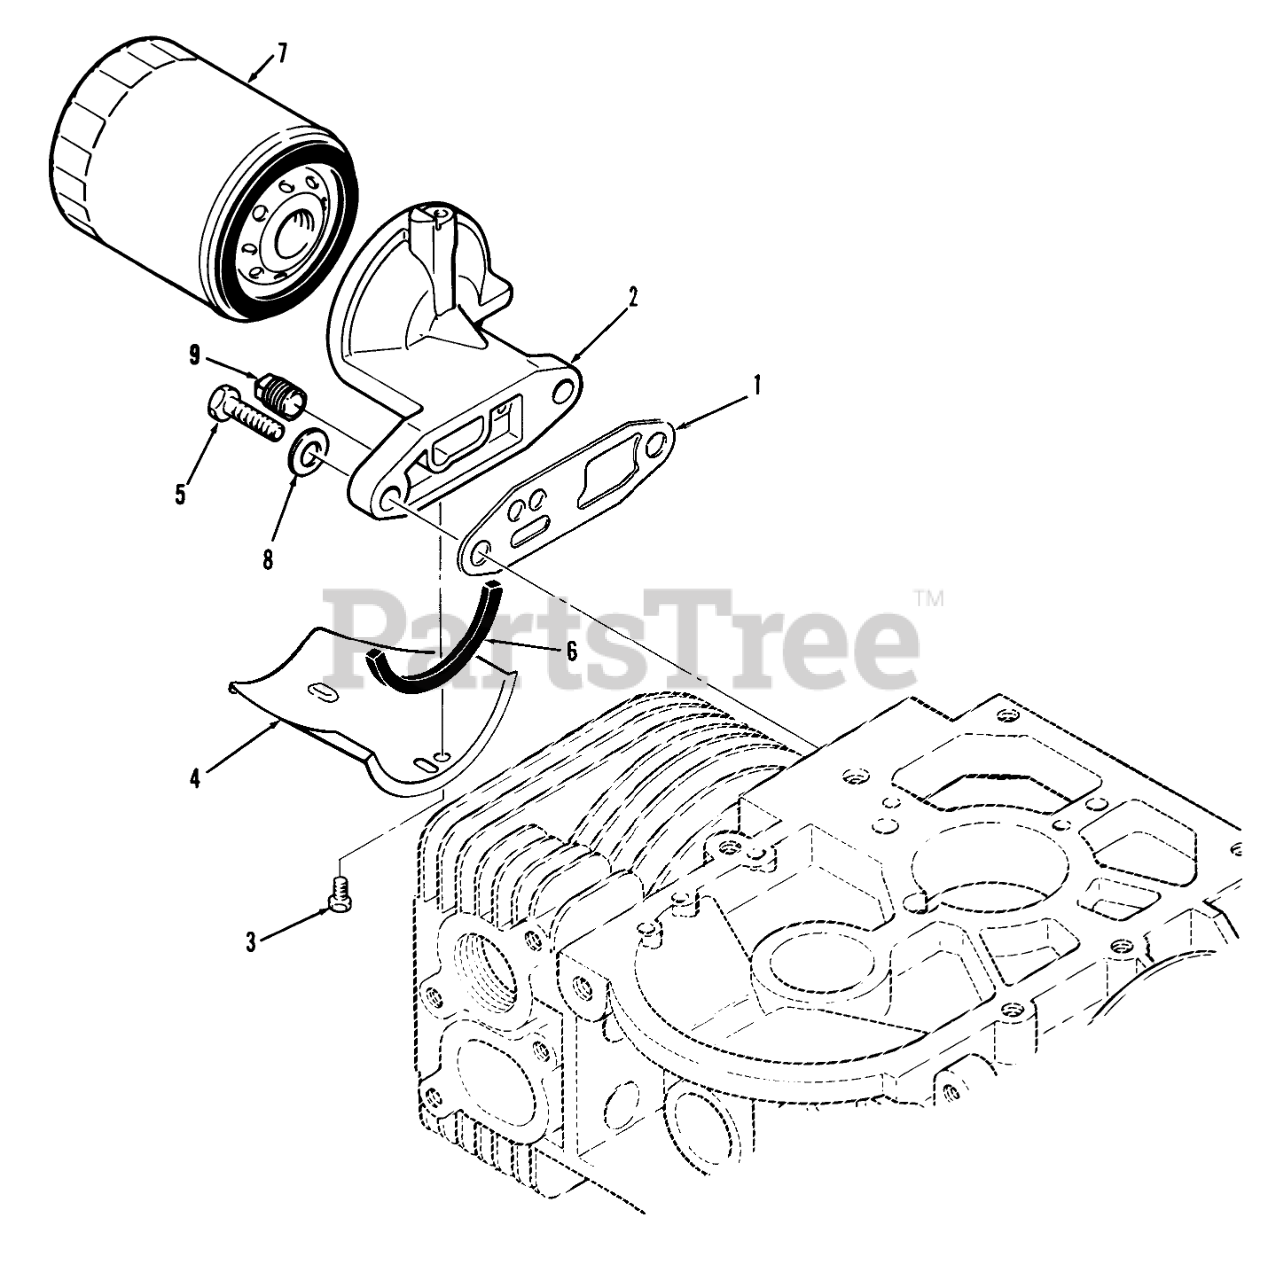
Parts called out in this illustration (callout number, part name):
1	Gasket
2	Adapter
3	Bolt
4	OIL-DRAIN
5	HHCS 5/16-18 X 1
6	OIL-DRAIN SEAL
7	OIL FILTER
8	WASHER
9	Plug
